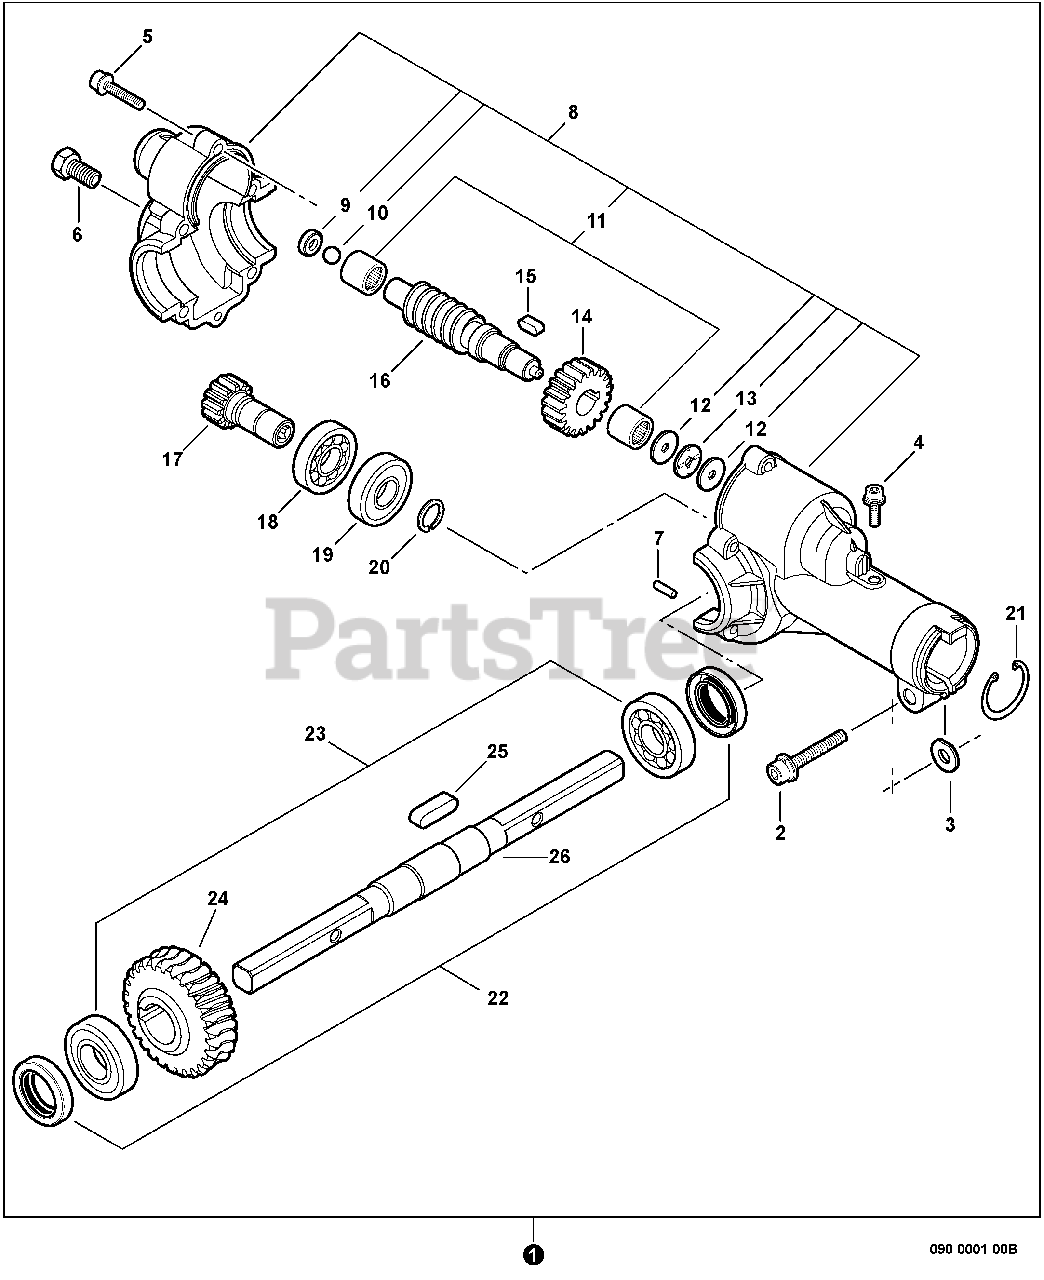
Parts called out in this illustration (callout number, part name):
1	GEAR CASE ASSY
2	BOLT 6×30
3	D-WASHER
4	BOLT 5×12
5	BOLT 5×20
6	BOLT 8×10
7	PIN, LOCATING 4×20
8	GEAR CASE ASSY
11	BEARING, NEEDLE 10
13	BEARING, THRUST
14	GEAR, SPUR 19 TOOTH
15	KEY, WOODRUFF
16	GEAR, WORM
17	GEAR, SPUR 12 TOOTH
18	BEARING, BALL 6901
19	BEARING, BALL 6901
20	RING, SNAP Ø12
21	RING, RETAINING Ø24
22	SEAL, OIL 17
23	BEARING, BALL 6003
24	GEAR, WORM WHEEL
25	KEY, WOODRUFF
26	SHAFT, WORM WHEEL
